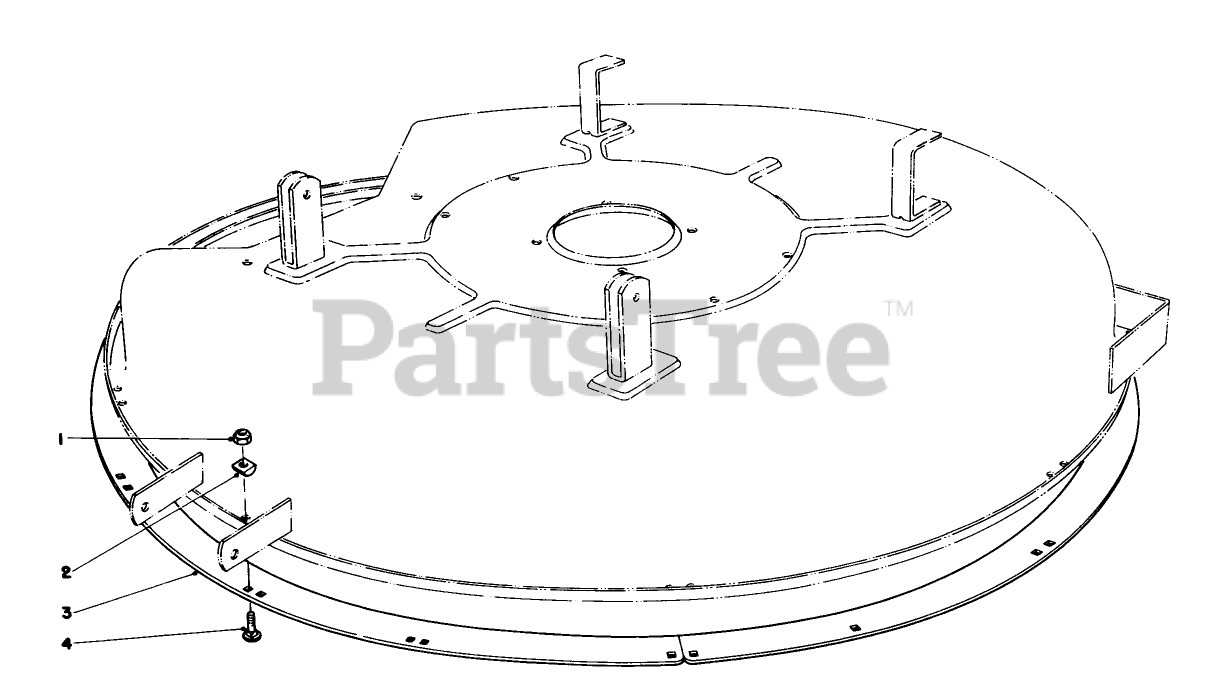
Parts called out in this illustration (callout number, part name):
1	NUT-LOCK, NI
3	DECK RING *B
4	BOLT-CARR
